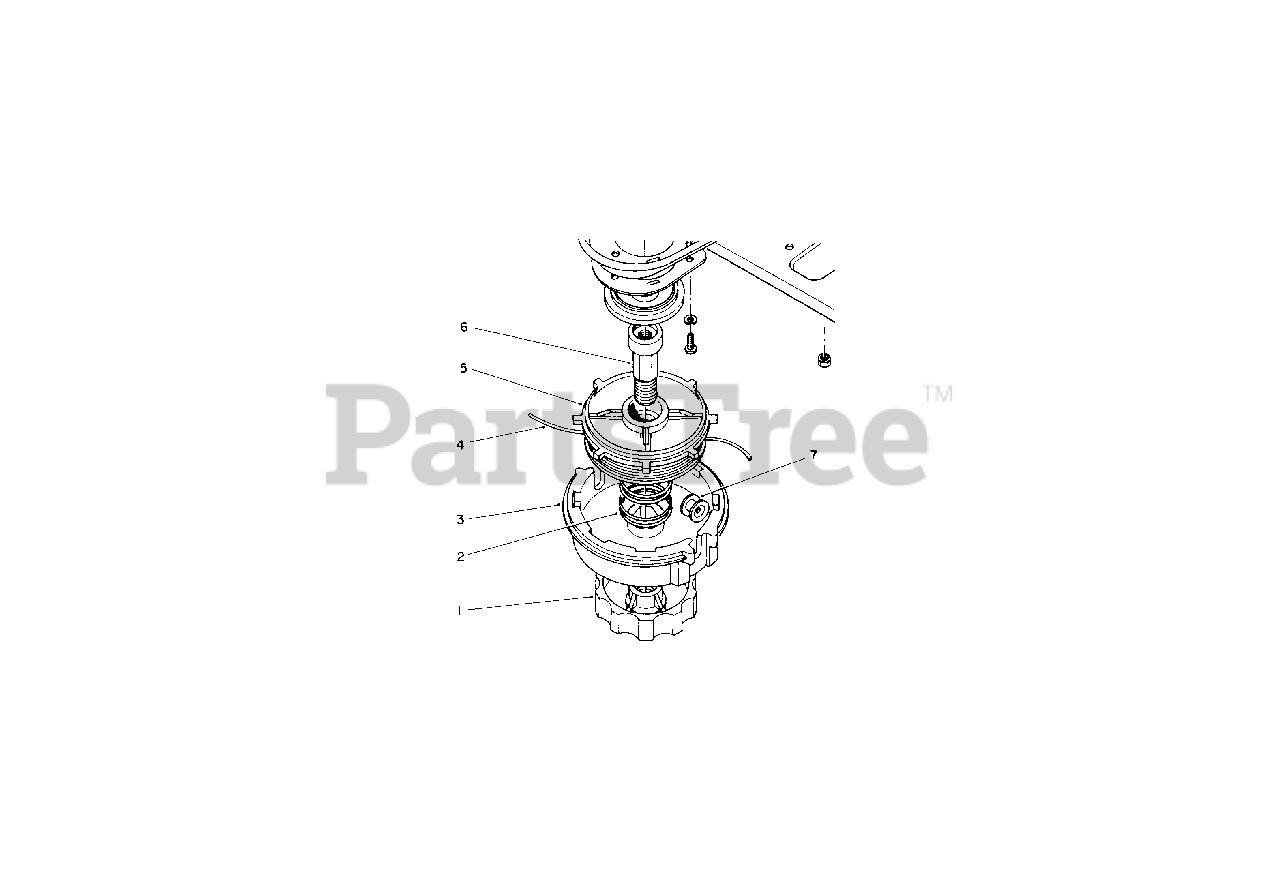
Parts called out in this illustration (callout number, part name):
1	Knob-L.H.
3	Spool Housing
4	Line-Cutting .08 Dia. 38' (Optional)
5	Spool-Inner
